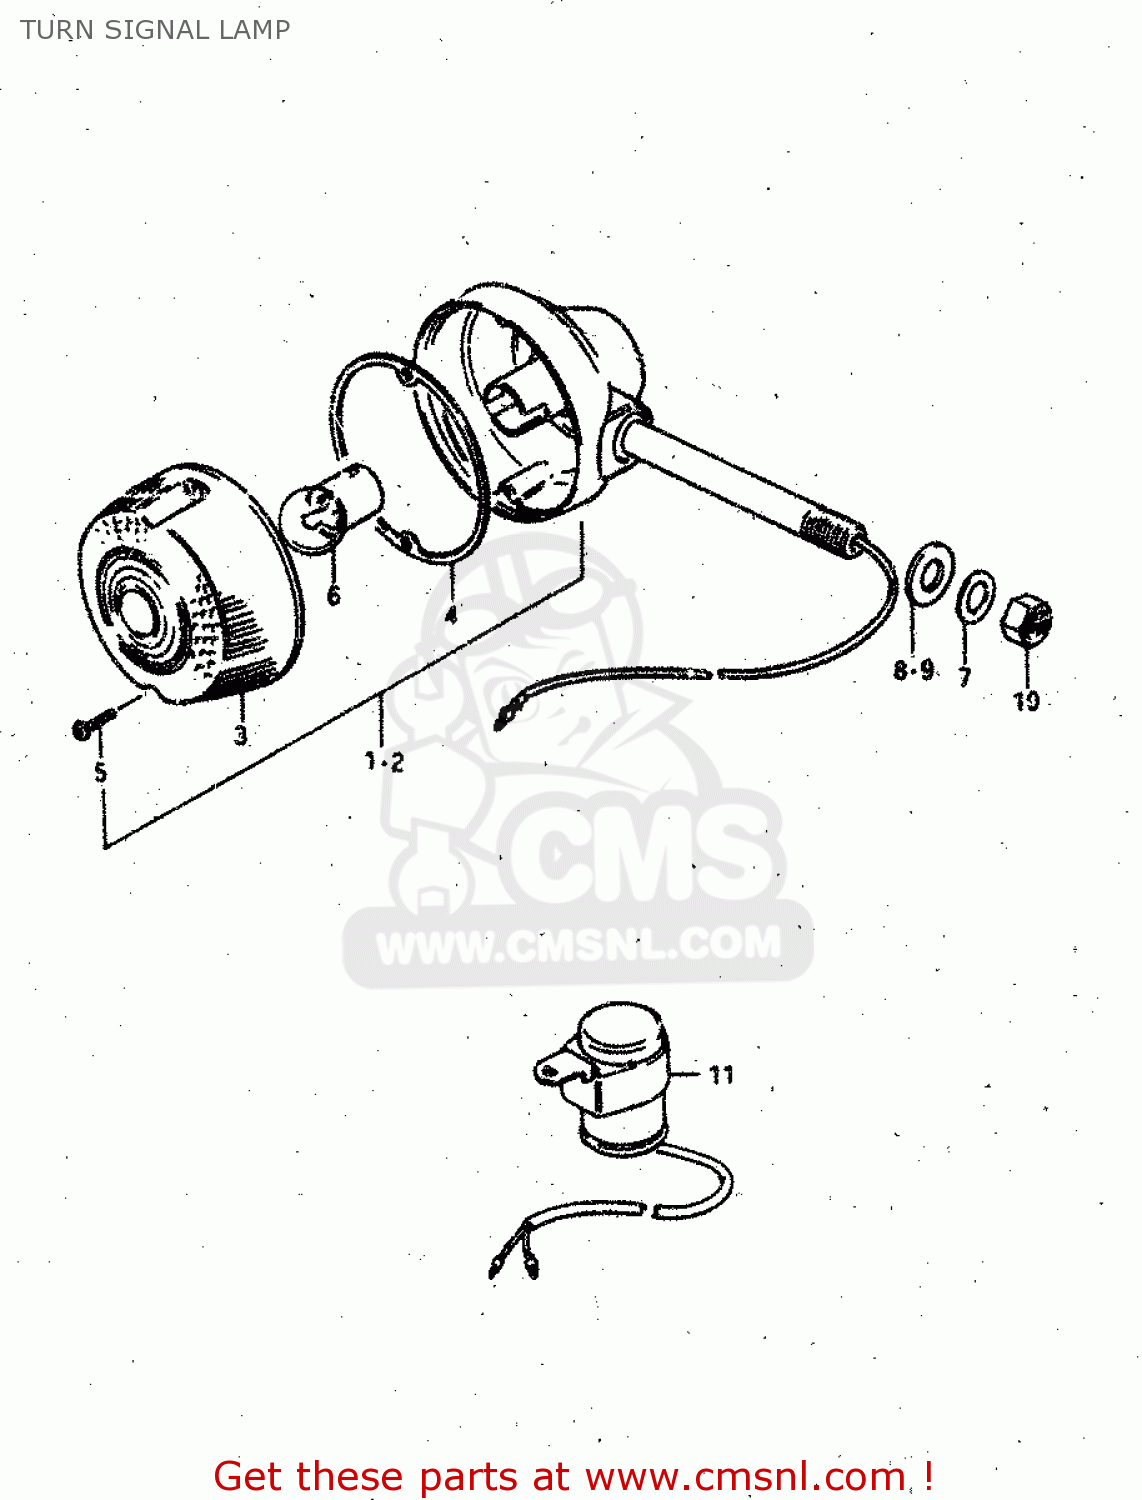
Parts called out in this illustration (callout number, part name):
1	LAMP, FRONT TURN SIGNAL
2	LAMP ASSY,RR TURNSIGNAL
3	LENS
4	GASKET (NAS)
5	SCREW
6	BULB(6V8W,STANLEY,A4115)
7	WASHER
8	WASHER(10.5X24X3.2)
9	WASHER (10.5X22X2.3)
10	NUT
11	RELAY, TURN SIGNAL
